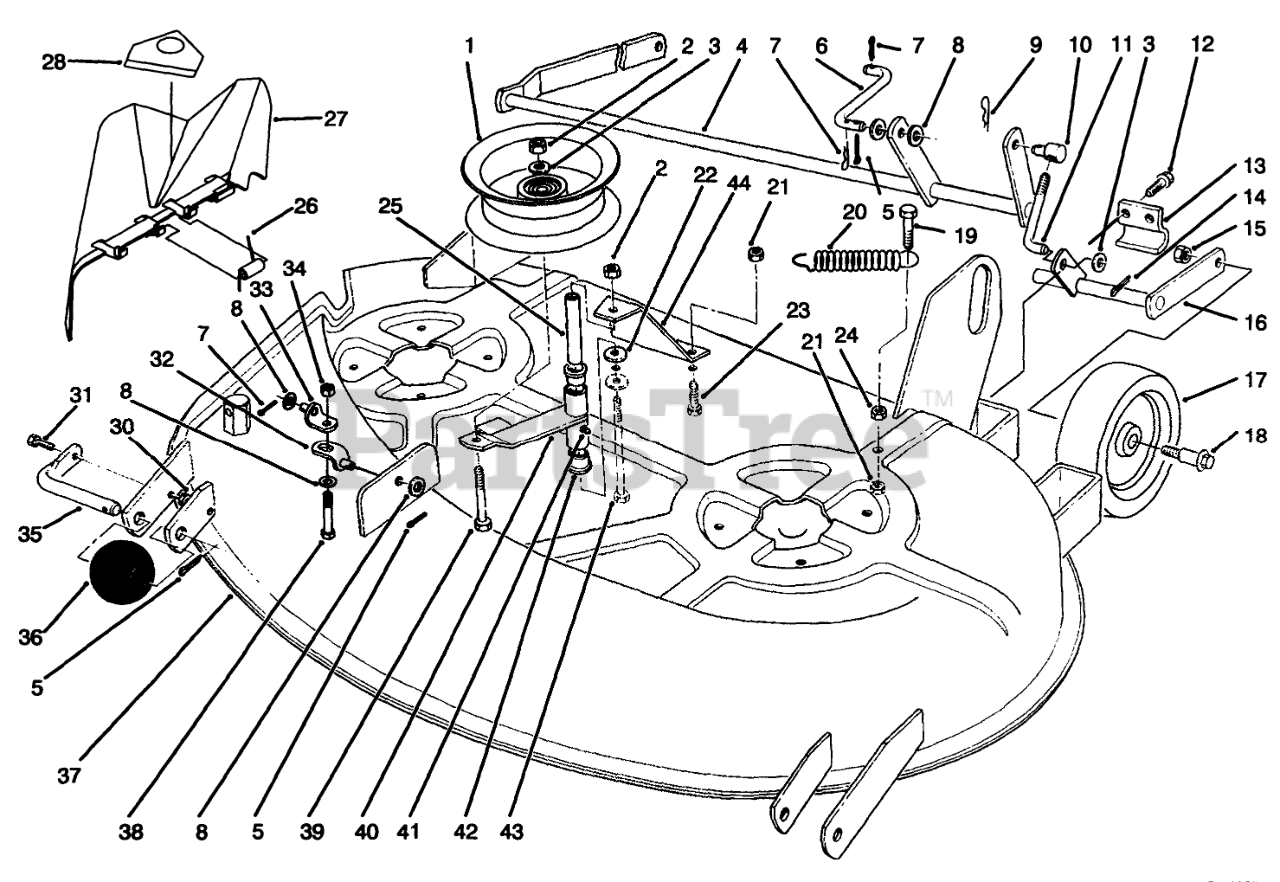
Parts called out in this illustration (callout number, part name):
1	PULLEY-IDLER
2	NUT-LOCK, NI
3	WASHER-FLAT
4	SHAFT-RH
5	PIN-COTTER
6	LINK-REAR
7	Hairpin
8	WASHER-FLAT
9	Hairpin
10	TRUNNION
11	ROD-LIFT
12	Bolt
14	PIN-COTTER
15	NUT-HEX
16	SHAFT-LH
17	WHEEL
18	BOLT-SHOULDER
19	SCREW-HH
20	SPRING-EXTENSION
21	NUT-LOCK, NI
22	WASHER
23	SCREW-HH
24	NUT-HEX
25	SPACER
26	SPRING
27	DEFLECTOR ASM
28	DECAL-DANGER
30	NUT-LOCK, NI
31	SCREW-HH
32	BRACKET-LIFT, LOWER
33	BRACKET-LIFT, UPPER
34	NUT-JAM
35	SHAFT-ROLLER
36	ROLLER
37	Deck/Safety Decal Assy. (Incl. Ref.#1 & 11 pg.3)
38	SCREW-HH
39	SCREW-HH
40	WLDMT-IDLER ARM (BLACK)
41	FITTING-GREASE
42	BUSHING
43	SCREW-HH
